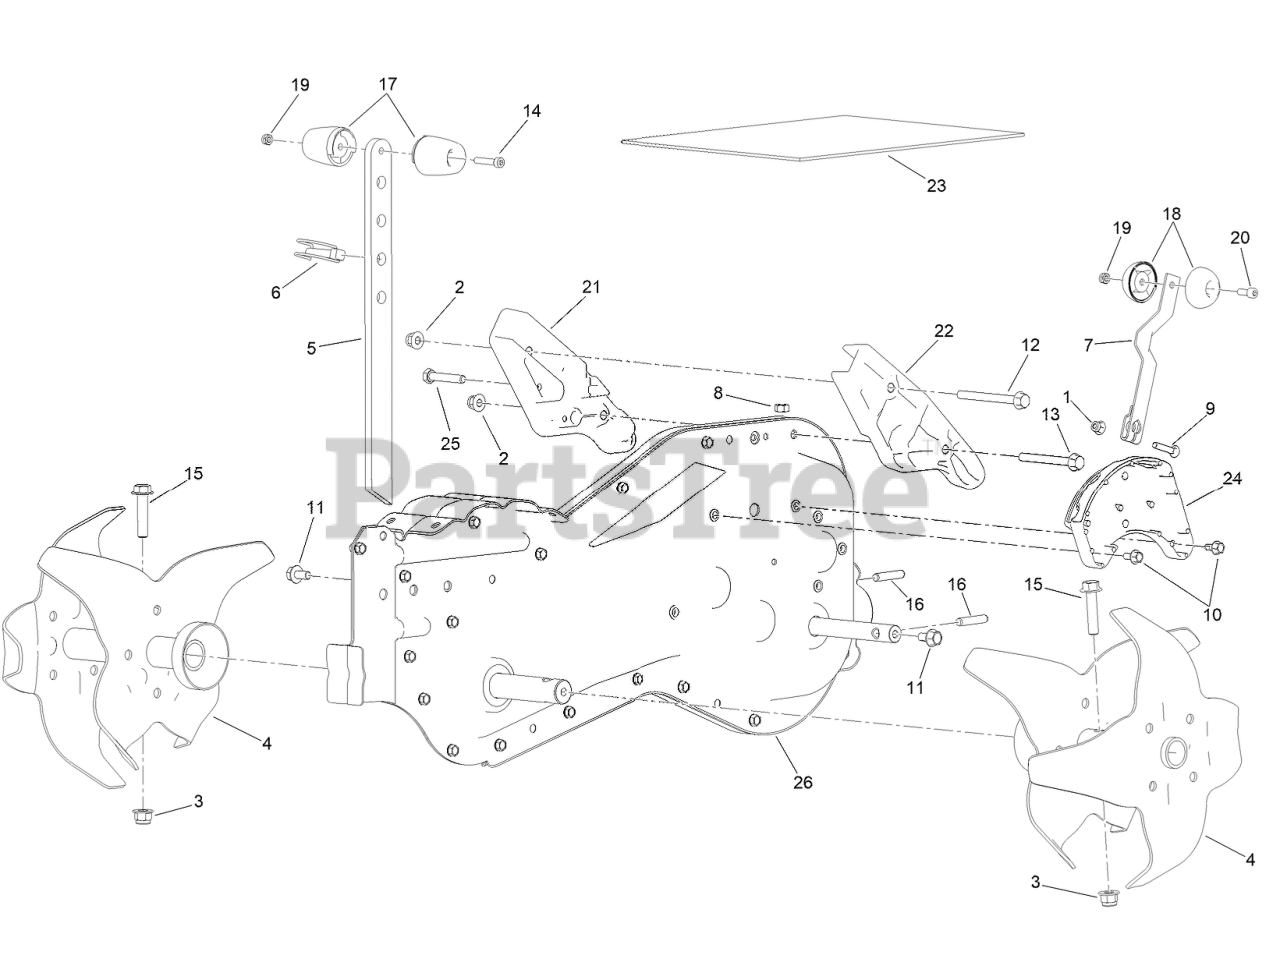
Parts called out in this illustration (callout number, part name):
1	NUT-HEX
2	NUT-HEX
3	NUT-HEX
5	STAKE-DRAG
6	PIN-LOCK
7	ARM-SHIFTER
8	NUT-HEX
9	SCREW-CRG
10	SCREW-HF
11	SCREW-HF
12	SCREW-HF
13	SCREW-HF
14	SCREW-SHCS
15	SCREW-HHF
16	PIN-DOWEL
17	HANDLE
18	HANDLE-SHIFT
19	NUT-HEX
20	SCREW-SHCS
21	MOUNT-HANDLEBAR, LEFT
22	MOUNT-HANDLEBAR, RIGHT
23	BAG-MANUAL
24	SHIFT SELECTOR
25	SCREW-HHCS
26	TRANSMISSION ASM
